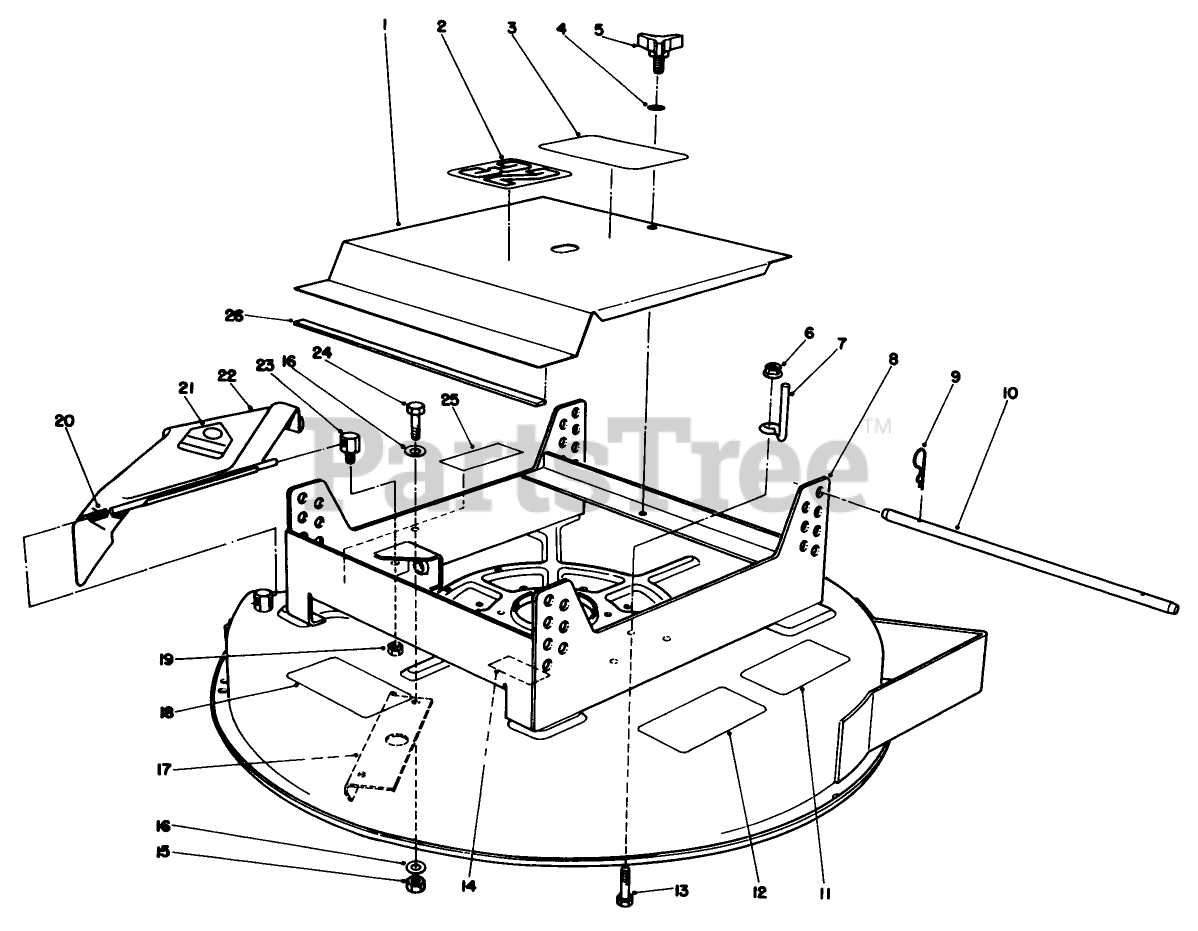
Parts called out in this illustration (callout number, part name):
1	Cover
2	DECAL
3	DECAL
4	WASHER-FLAT
5	Knob
6	NUT-HF
7	Guide-Belt
8	Deck W.A.
9	PIN-HAIR
10	ROD-SUPPORT
11	DECAL
12	Decal
13	SCREW-HH
14	DECAL-DANGER
15	NUT-LOCK, NI
16	WASHER-PLAIN
17	Baffle Deck
18	DECAL-DANGER, THROWN OBJECT
19	NUT-LOCK, SIDE
20	SPRING
21	DECAL-DANGER
22	Deflector Assy. (Incl. Ref. #21)
23	POST-PIVOT
24	SCREW-HH
25	DECAL-DANGER
26	STRIP-MAGNETIC
